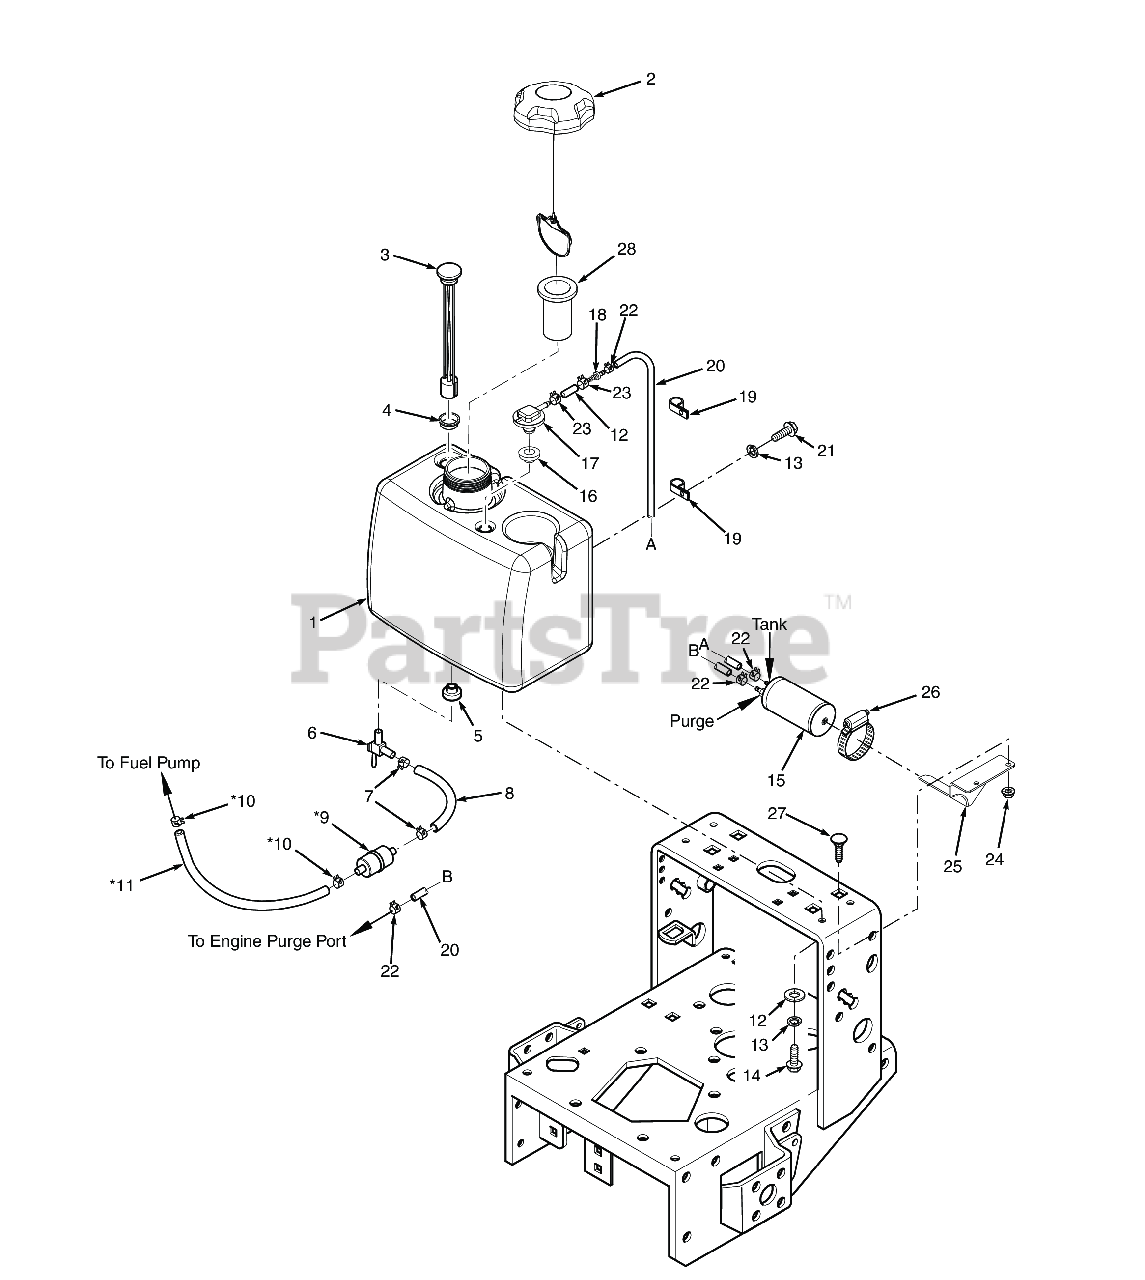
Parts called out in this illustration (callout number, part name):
1	Fuel Tank Assembly (incl. #2, 3, 5, 6, 17, 18)
2	Fuel Cap w/ Tether (E.P.A.)
2	Fuel Cap w/Tethered - California Models Only
3	Fuel Gauge Assembly
4	Grommet, Fuel Gauge
5	Bushing, 0.56" Dia. Viton
6	Valve, Fuel Shut Off w/Screen
7	Clamp, Fuel Hose 1/4" Hose I.D.
8	Fuel Hose, 1/4" I.D. Non-Perm (791DFI Fuel Return) - Order by Inch
9	Fuel Filter
10	Clamp, Fuel Hose
11	Fuel Hose
12	Hose, 1/4" Vapor Recovery (order by inch)
13	Lockwasher, 5/16 (.317 x .586 x .078) Helical Spring
14	Bolt, Heax Head 5/16-18 x 1" (48V / 52V)
15	Carbon Canister - SVR-36A / SVR-48V
16	Grommet, Viton,
17	Remote Vent, No Valve
18	Mender, 1/4 x 3/16 w/0.02 Hole
19	Clamp, Cable - .375 Dia.
20	Hose, Vapor Recovery 3/16" (order by inch)
21	BOLT, SERRATED FLANGE HEX HEAD 5/16-18 X 3/4"
22	Clamp, Vapor Recovery Hose 3/16"
23	CLAMP, FUEL HOSE(KAWASAKI ONLY)
24	Nut, Serrated Flange 5/16-18 (Right Front Engine Mounting, Briggs and Kohler Only)
25	Bracket, Canister Mounting
26	Clamp, 3-1/2" Max. Dia.
27	Bolt, Carriage 5/16-18x1" (large frame units only)
28	Tube, Fuel Tank Insert - 4"
